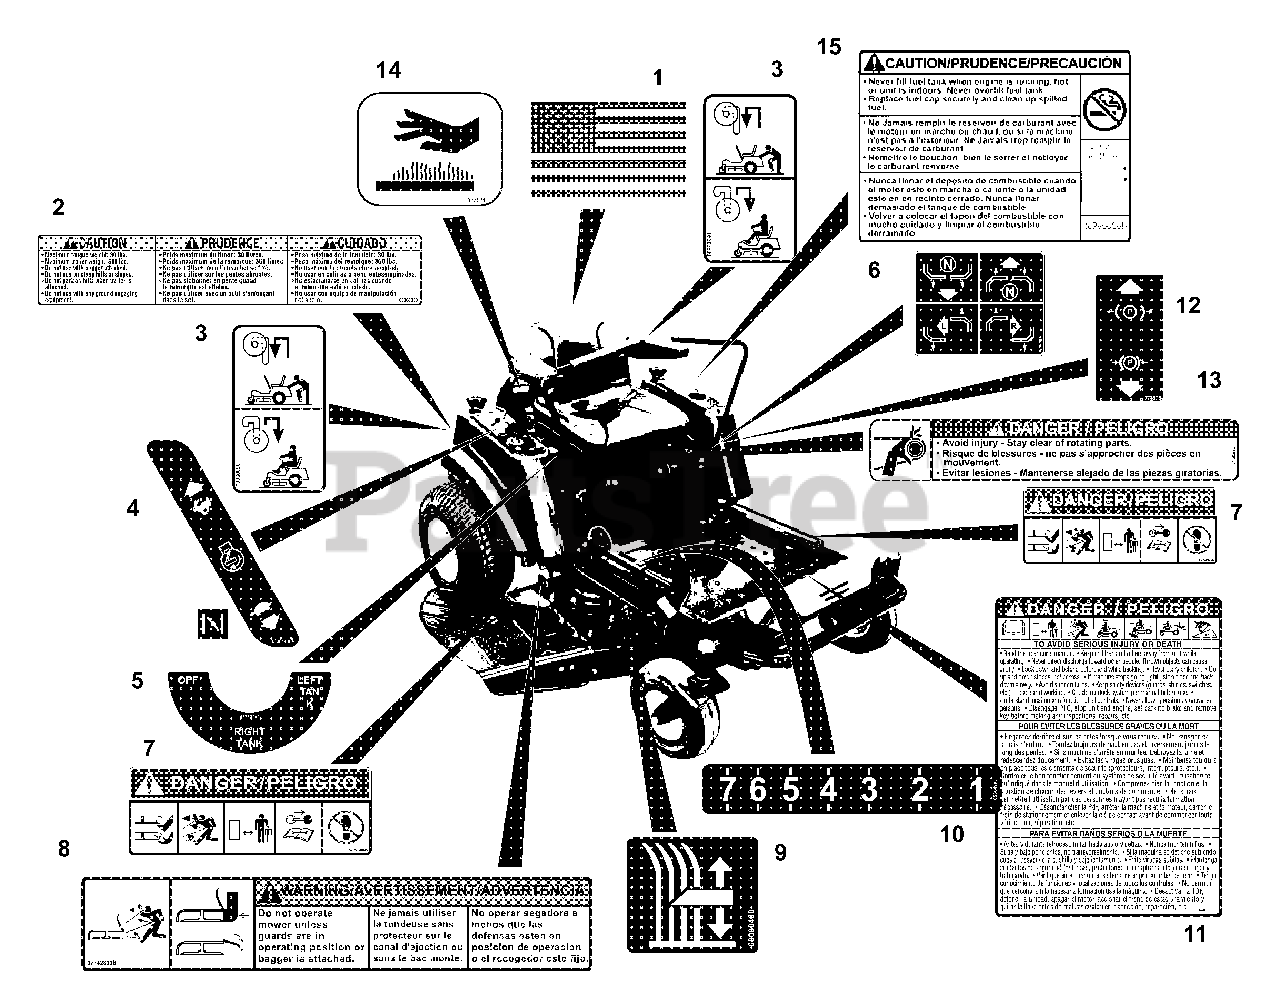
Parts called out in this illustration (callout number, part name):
1	Decal, American Flag
2	Decal, Trailer Hitch
3	Decal, Transmission Disconnect
4	Decal, Control
5	Decal, Fuel Value
6	Decal, Instructional Steering
7	Decal, Mower Pan Head Danger
8	Decal, Warning
9	Decal, Cut Height
10	Decal, Cut Height Zoom
11	Decal, Bilingual Danger
12	Decal, Parking Brake Lever
13	Decal, Danger
14	Decal, Hot Surface
15	Decal, Fuel Warning
